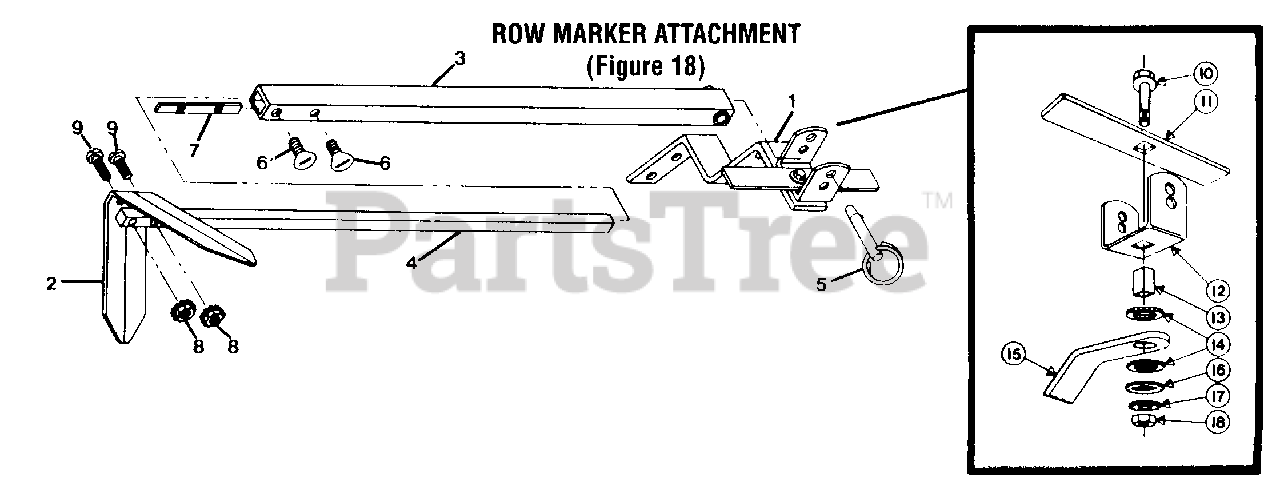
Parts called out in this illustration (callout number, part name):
1	Main Support & Yoke Assy-complete
2	Marker blade-blade only
3	Marker arm-main arm
4	Marker arm-extension arm with stop pin
5	Hitch Pin
6	Thumbscrew-1/4-20 x 1/2"
7	Nut Bar
8	Nut-hex, #10-24 with star washers
9	Screw-round hd., #10-24 x 1
10	Bolt-flanged, self-locking, 3/8-16 x 1-1/2"
11	Stop Bar
12	Yoke
13	Tube Key-square
14	Washer - friction
15	Main Support
16	Washer - square hole
17	Washer-disc spring
18	Nut-hex, 3/8"-16
